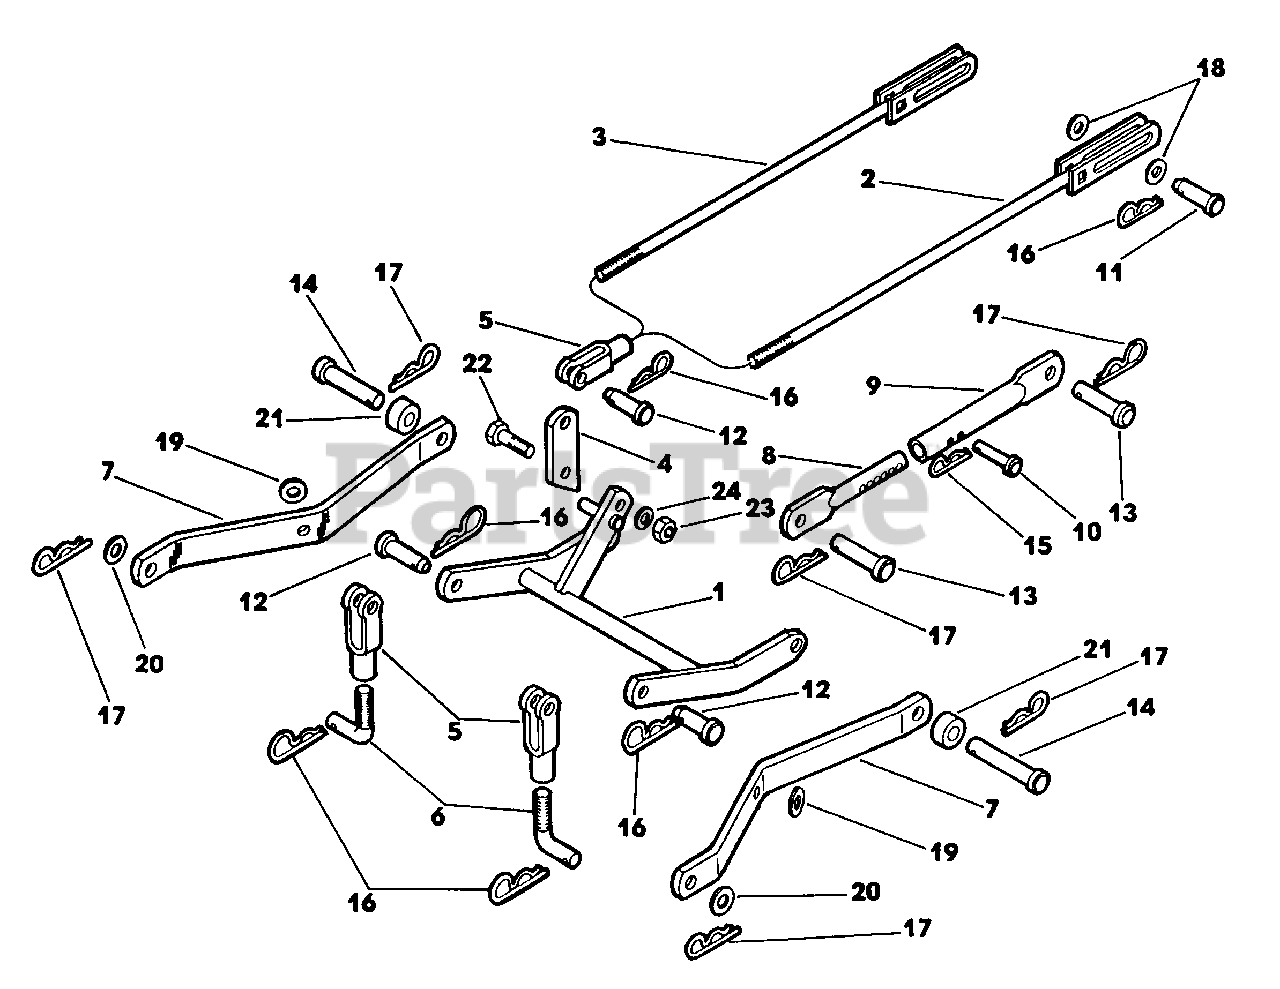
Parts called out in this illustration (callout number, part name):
1	Lift Frame Assembly
2	Lift Rod Assembly (Long)
3	Lift Rod Assembly (Short)
4	Lift Arm Extension
5	Clevis
6	Pin-Lift Adjustment
7	Lift Link-Side
8	Lift Link-Inside Half
9	Lift Link-Outside Half
10	Clevis Pin
11	Clevis Pin
12	Clevis Pin
13	Clevis Pin
14	Clevis Pin
15	Spring Clip
16	Spring Clip
17	Spring Clip
18	Washer, Flat
19	Washer, Flat
20	Washer, Flat
21	Spacer (Gear Drive Tractors Only)
22	Cap Screw, Hex Hd
23	Nut, Hex
24	Washer, Spring Lock
